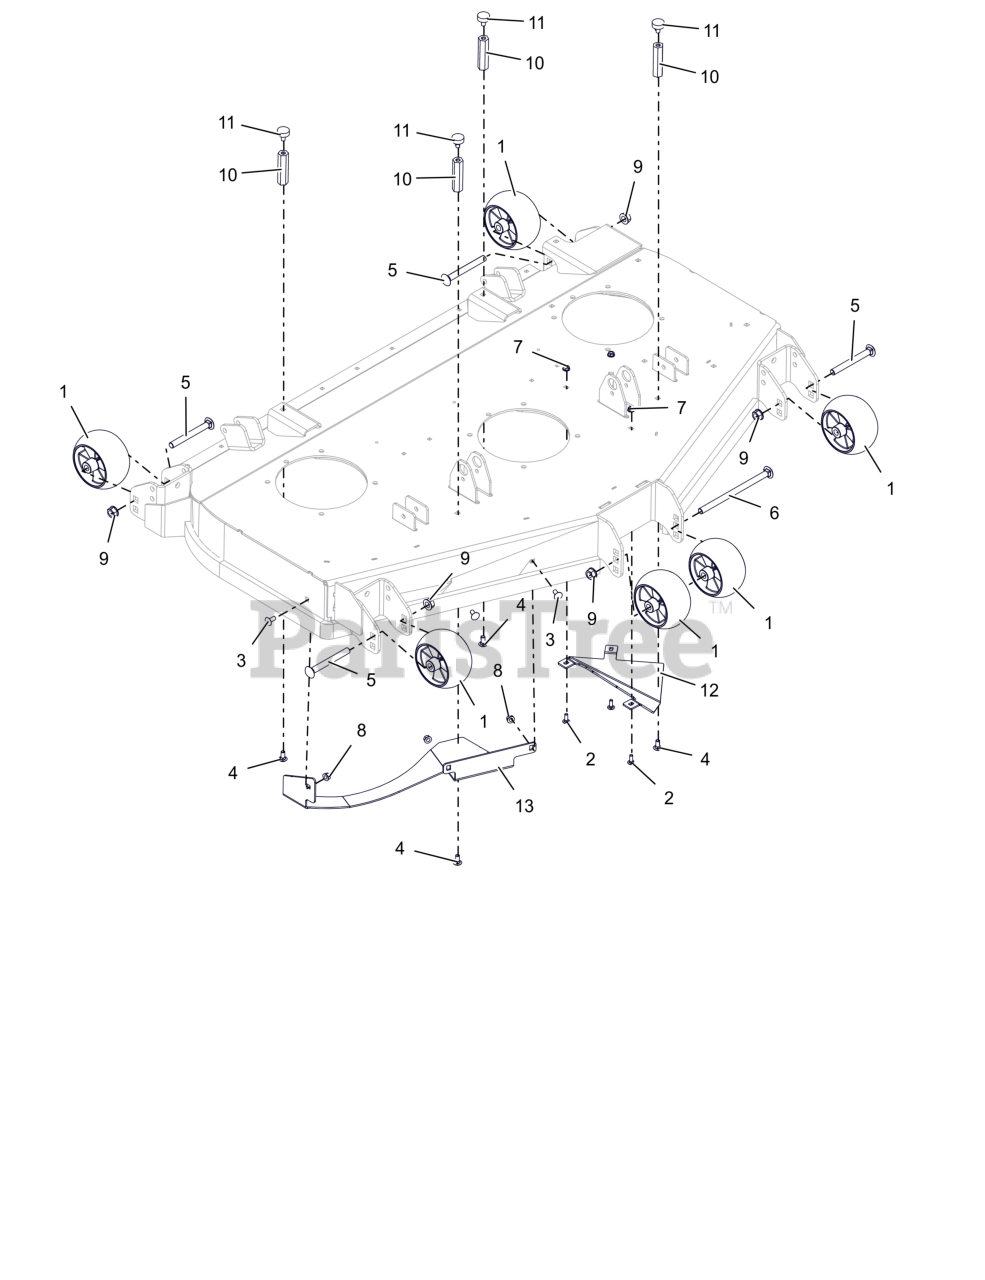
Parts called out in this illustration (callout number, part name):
1	WHEEL, ANTI SCALP - 5X3 CTR W/RIBS
2	BLT, RHSN .25-20X.750 G5 ZCC
3	BLT, RHSSN.31-18X.750 G5 ZCC
4	BTL,RHSN .313-18 X 0.75 G5 ZCC LT
5	BOLT, RHNS .50-13X4.50 G5 ZCC NS
6	BOLT, RHNS .50-13X8.00 G5 ZCC NS
7	NUT-LK-CTR-FLG .25-20 ZC120
8	NUT,LK-CTR-FLG .31-18 GF ZCC
9	NUT-LK-CTR-FLG .500-13 GG ZCC
10	NUT, COUPLING .31-18 X 3.00
11	BUMPER, RUBBER
12	BAFFLE- 52" TRIANGLULAR INSERT
13	DEFLECTOR- 52" BOLT-IN BAFFLE
